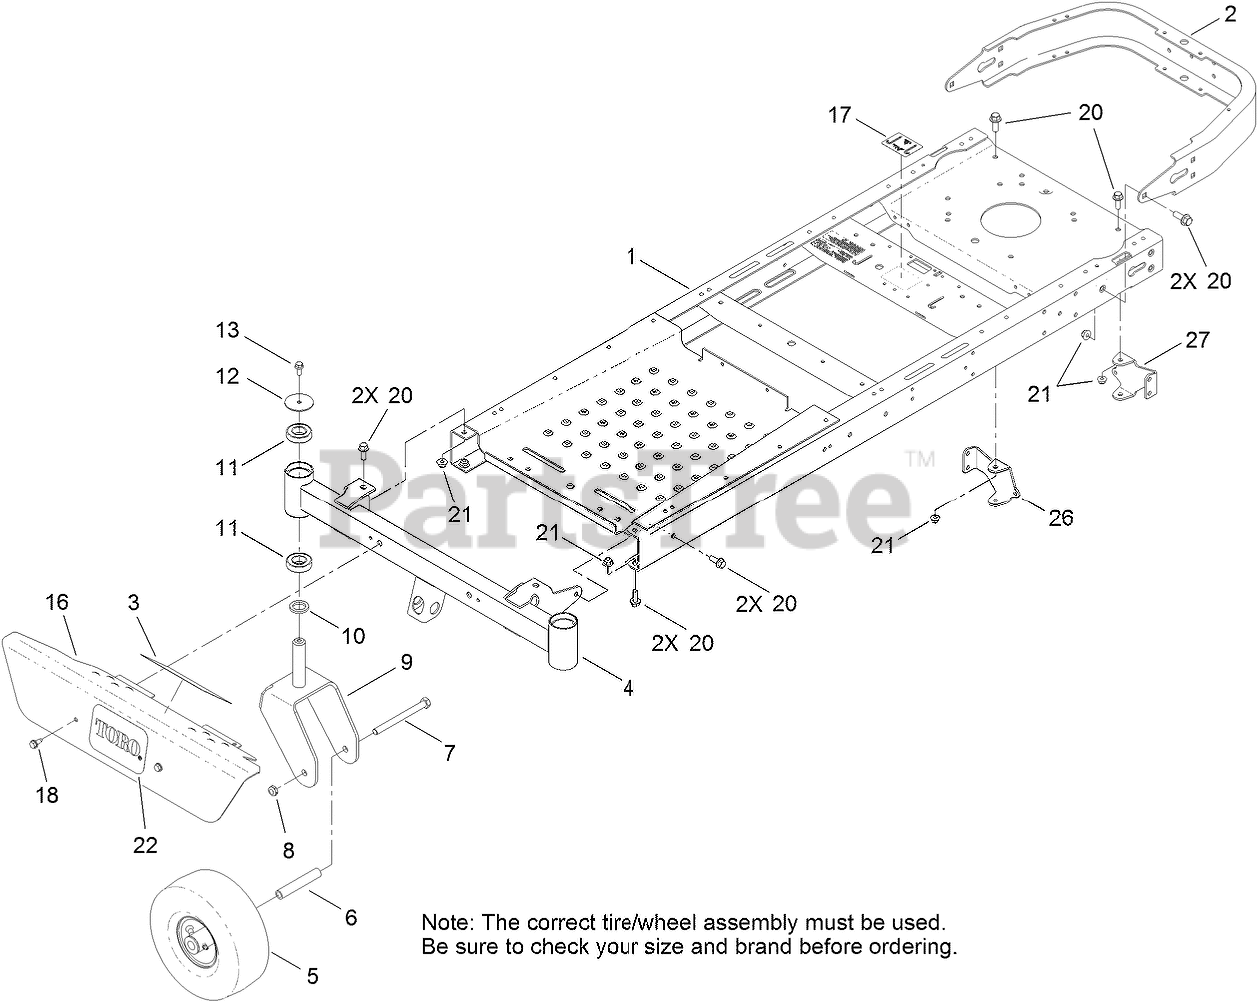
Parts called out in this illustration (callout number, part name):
1	FRAME ASM
2	BUMPER-REAR
3	DECAL-DANGER
4	AXLE-FRONT
5	CASTER WHEEL ASM (Kenda)
5	CASTER WHEEL ASM (CST)
6	BUSHING-SPANNER
7	SCREW-HH
8	NUT-LOCK, NI
9	FORK-CASTER
10	WASHER-THRUST
11	BEARING-BALL
12	WASHER
13	SCREW-HHF
16	FOOTREST
17	DECAL-TRANSPORT
18	SCREW-HWHTF
20	SCREW-HHF
21	NUT-HF, NI
26	MOUNT-HYDRO, REAR (RH)
27	MOUNT-HYDRO, REAR (LH)
